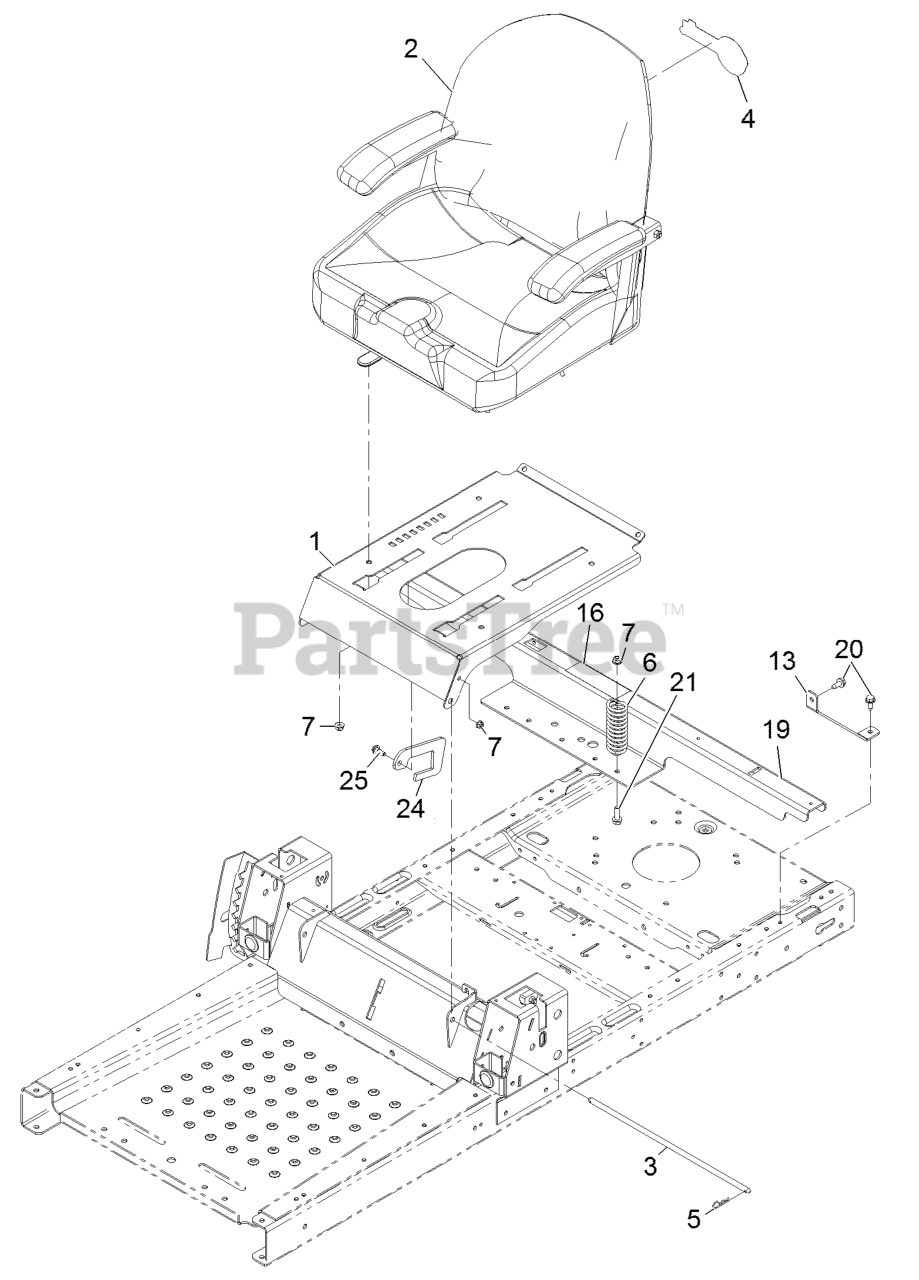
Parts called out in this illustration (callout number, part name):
2	SEAT ASM
3	ROD-STOP
5	PIN-COTTER
6	SPRING-COMPRESSION
7	NUT-HF, NI
13	SUPPORT-TANK, REAR
16	DECAL-SERVICE, CE
19	SUPPORT-POD
20	Screw-HWH 5/16-18 X 3/4 Tf
21	SCREW-HHF
24	STOP-SEAT
25	SCREW-SHOULDER
